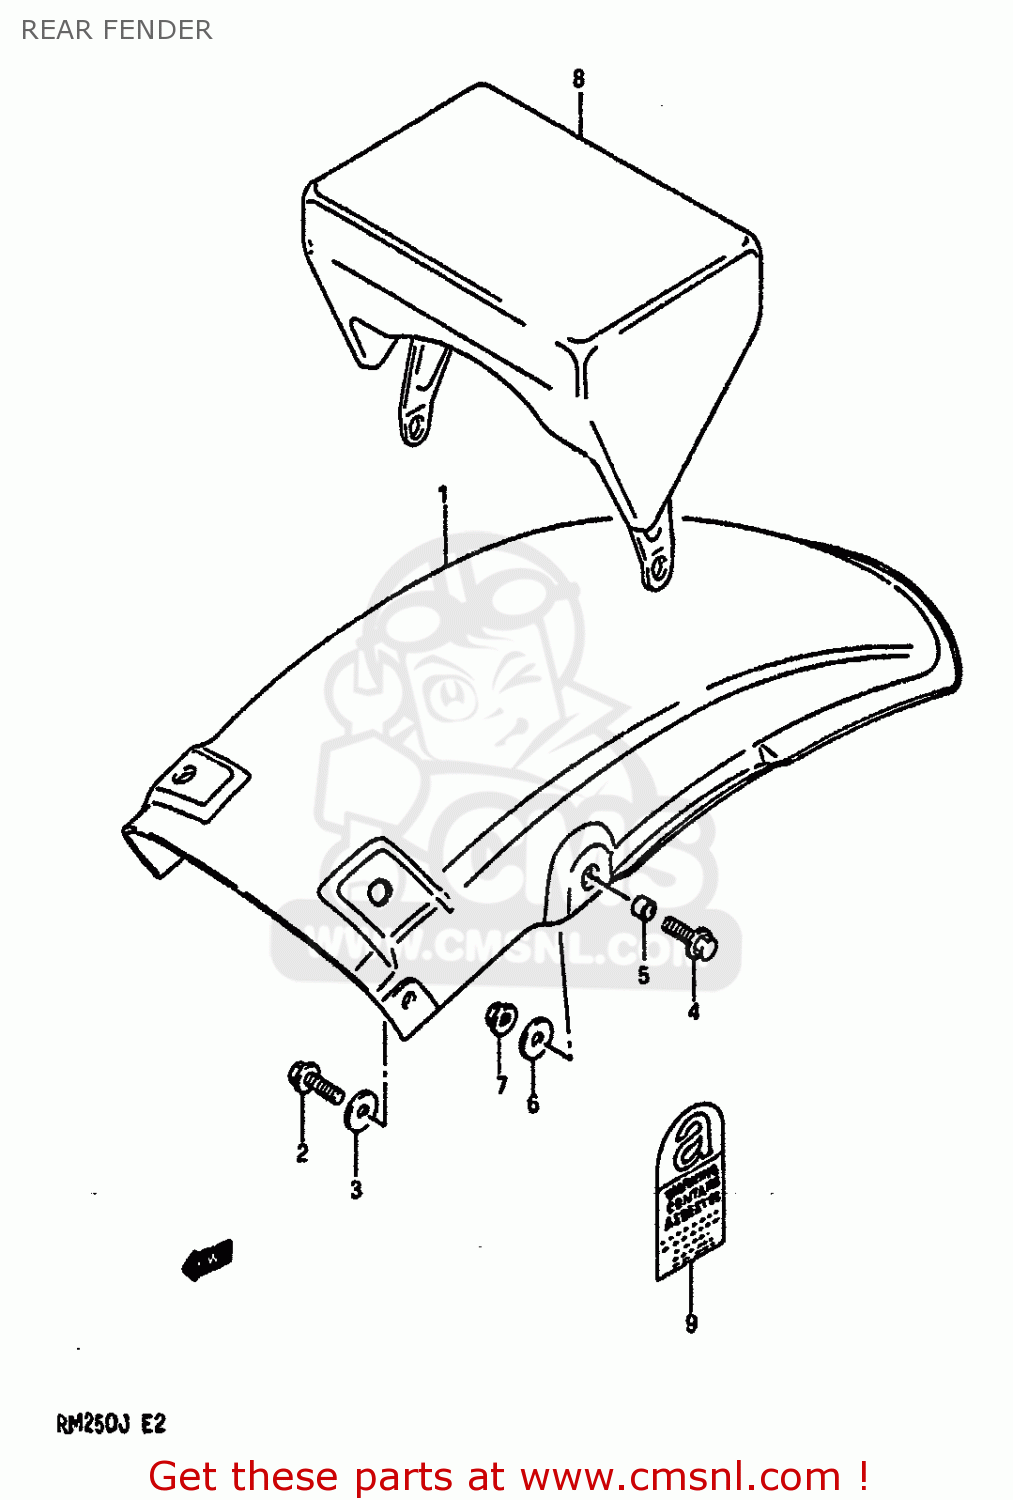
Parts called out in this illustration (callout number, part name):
1	BODY,RR FENDER RR
2	BOLT
3	WASHER (6.5X20X1.2)
4	BOLT
5	SPACER
6	WASHER (6.5X20X1.2)
7	NUT
8	BAG ASSEMBLY,SEAT TAIL
9	LABEL,ASBESTOS WARNING
